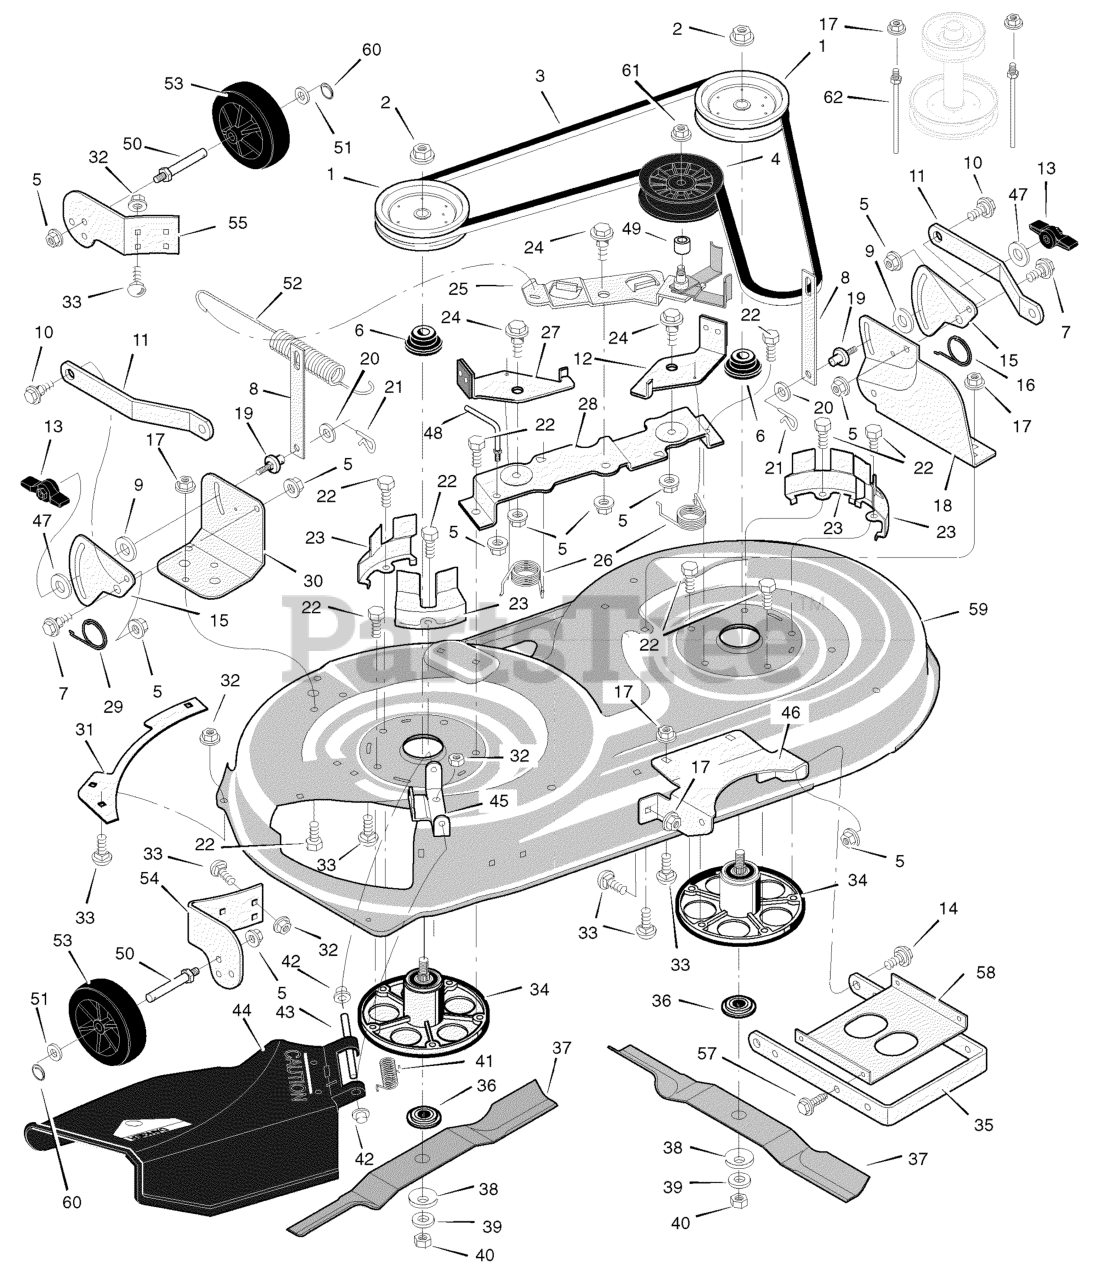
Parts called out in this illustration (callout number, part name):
1	Pulley, Jackshaft
2	Nut, Hex
3	Belt, Mower Drive
4	Pulley, Idler
5	Nut, Flange
6	Spacer, Pulley
7	Bolt, Shoulder
8	Link, Lift
9	Pad, Friction
10	Bolt, Shoulder
11	Bracket, Suspension
12	Pad Assembly, Left Brake
14	Bolt, Shoulder
15	Plate, Suspension
16	Spring
17	Nut, Flange
18	Bracket, Suspension
19	Pin, Hanger
20	Washer
21	Pin, Hair
22	Bolt
23	Cover, Pulley
24	Bolt, Shoulder
25	Arm, Idler
26	Spring
27	Pad Assembly, Right Brake
28	Bracket, Brake
29	Spring
30	Bracket, Suspension
31	Plate
32	Nut, Flange
33	Bolt, Carriage
34	Mandrell Housing
35	Bracket, Suspension
36	Adapter, Blade
38	Washer
39	Washer
40	Nut
41	Spring
42	Cap, Push On
43	ROD, Deflector
44	Deflector Assembly
45	Bracket, Deflector Hinge
46	Bracket, Front Hanger
47	Washer
48	Guide, Belt
49	Spacer
50	Bolt, Axle
51	Washer
52	Spring, Extension
53	Wheel, Gage
54	Bracket, Right Wheel
55	Bracket, Left Wheel
57	Screw
58	Stiffener
59	Housing, Blade *
60	Ring, Locking
61	Nut, Flange
62	Guide, Belt
